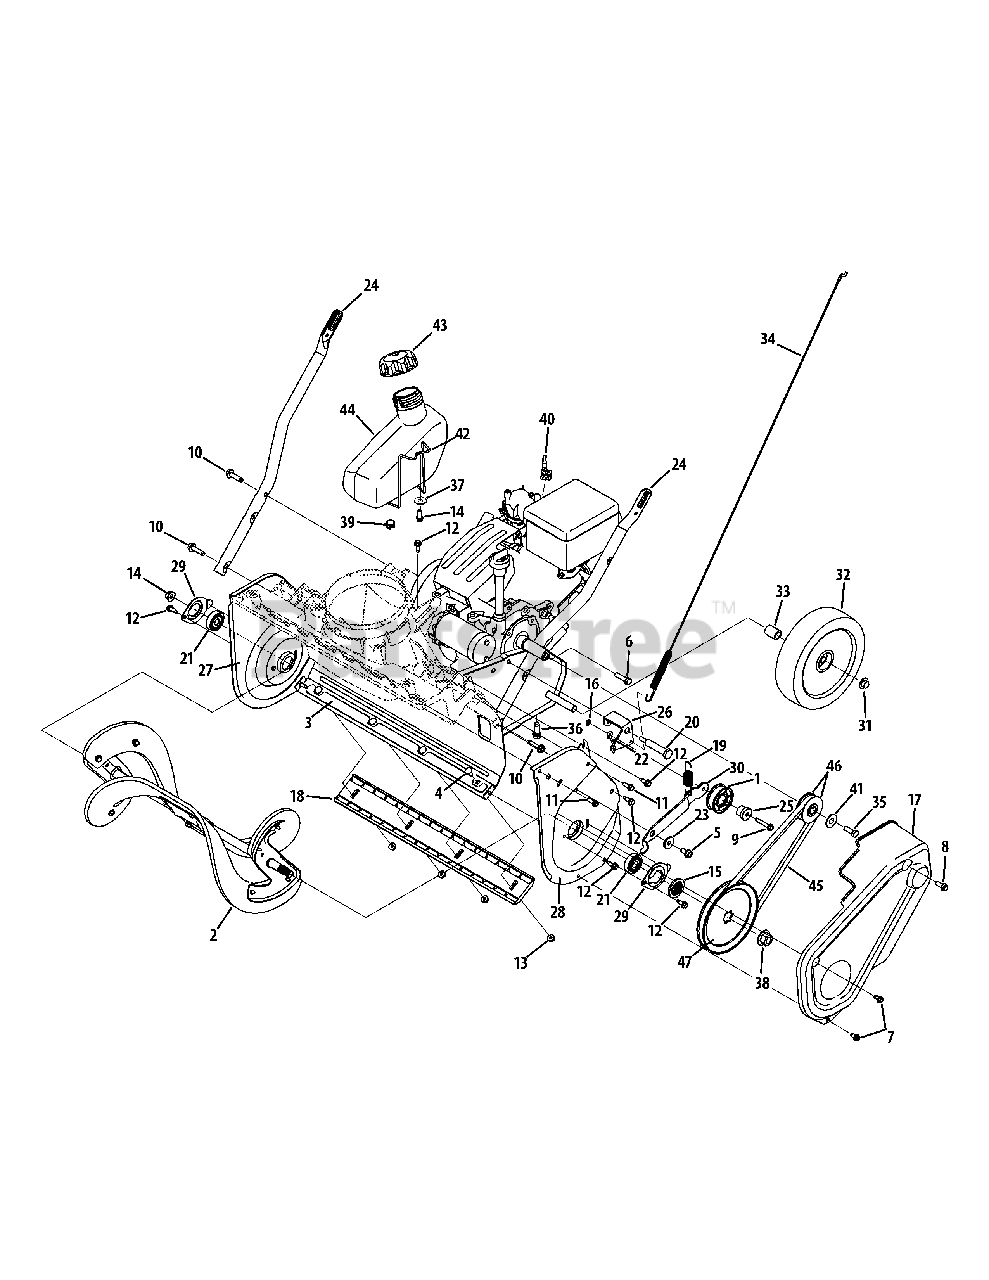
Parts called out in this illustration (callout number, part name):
1	Idler Pulley Assembly
2	Auger Assembly
2	Rubber Auger Paddle Kit
2	Hex Washer Screw, 1/4-20 x .750
2	Center Auger Bracket
2	Hex Washer Bolt 1/4-20 x.750
3	Frame Assembly
4	Carriage Screw, 1/4-20 x .62
5	Hex Washer Screw, 5/16-18 x .750
6	Hex Screw, 5/16-24 x 1.25
7	Hex Washer Screw, 1/4-20 x .500
8	Hex Lock Screw, 5/16-24 x .750
9	Hex Washer Screw, 1/4-20 x 1.500
10	Hex Washer Screw, 5/16-18 x 1.250
11	Hex Washer Screw, 1/4-15 x .750
12	Hex Washer Screw, 1/4-20 x .625
13	Flange Lock Nut, 1/4-20
14	Flange Lock Nut, 3/8-16
15	Pulley Hub
16	Push Nut, .25 x .50
17	Belt Cover
18	Shave Plate
19	Extension Spring, .70 x 3.035
20	Shoulder Bolt, 5/16-24 x .496 x 2.18
21	Ball Bearing, .5000 x 1.375 x .4375
22	Drive Cable Wire Support
23	Shoulder Spacer
24	Lower Handle
25	Shoulder Spacer
26	Idler Cable Bracket
27	RH Side Plate
28	LH Side Plate
29	Bearing Cup
30	Idler Bracket
31	Push Cap, 1/2
32	Wheel, 8 x 1.7
33	Sleeve Spacer, .525 x .78 x 1.07
34	Clutch Cable
35	Hex Lock Screw, 5/16-24 x .750
36	Hex Washer Screw, 3/8-16 x 1.000
37	Flat Washer, .265 x 1.000 x .030
38	Flange Nut, 7/16-20
39	Hose Clamp, .490
40	Choke Extension Lever
41	Flat Washer, .330 x 1.250 x .120
42	Gas Tank Wire Support
43	Fuel Cap
44	Fuel Tank
45	Belt, .500 x 35.06
46	Pulley Half, .625 x 2.25
47	Pulley, 1/2 x 6.00
